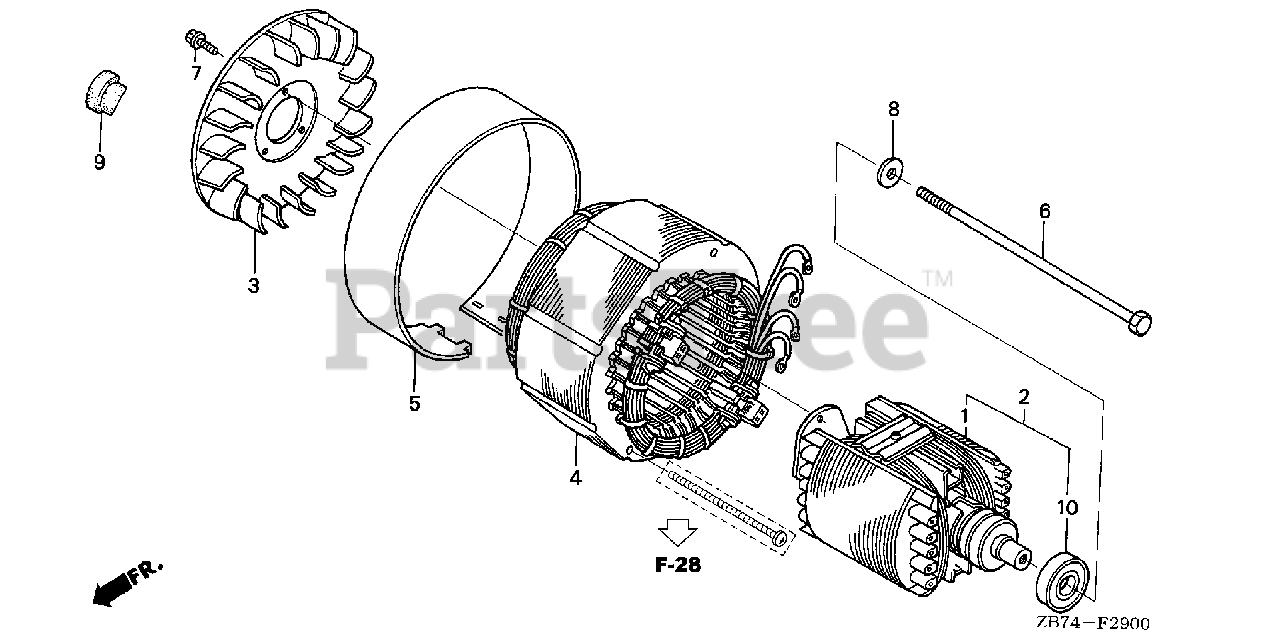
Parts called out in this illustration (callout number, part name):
2	ROTOR
3	FAN, GENERATOR COOLING
4	STATOR ASSY.
5	COVER, STATOR
6	BOLT, HEX. (10X210)
7	SCREW, TAPPING (5X14)
8	WASHER (10.5MM)
9	GROMMET, CRANKCASE
10	BEARING ASSY. (6204)
